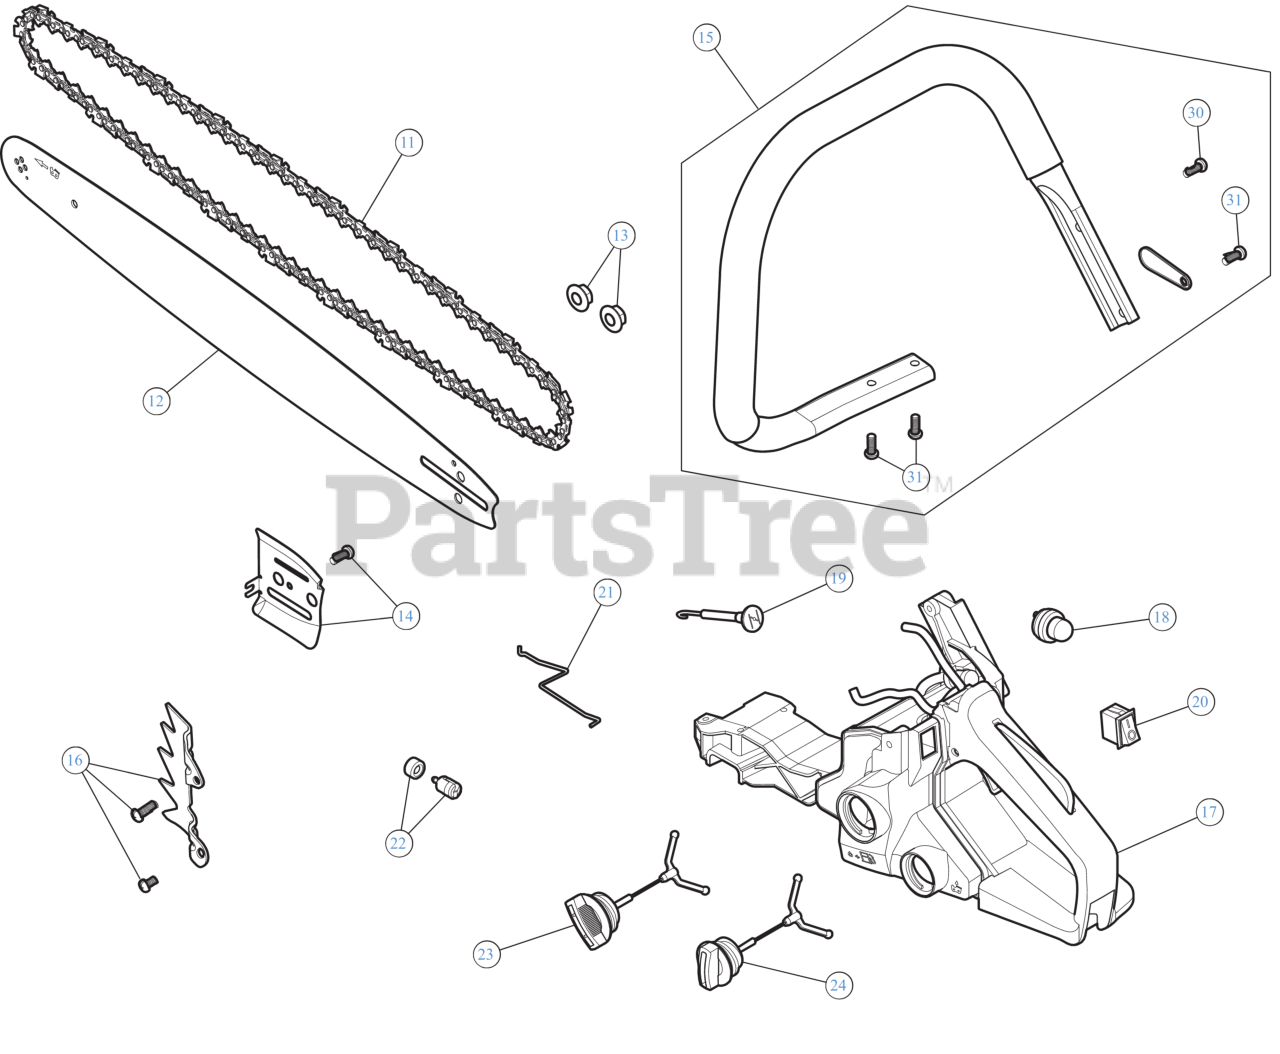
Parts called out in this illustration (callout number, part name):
11	14" CHAIN
11	16" CHAIN
11	CHAIN 18" TRILINK
12	14" BAR
12	16" BAR
12	18" BAR
13	NUT:BAR:M8
14	BAR PLATE
15	CHAINSAW HANDLE
16	SPIKE PLATE
17	FUEL TANK
18	PRIMER BULB
20	STOP SWITCH
21	Fuel Cap Assembly
22	OIL CAP
